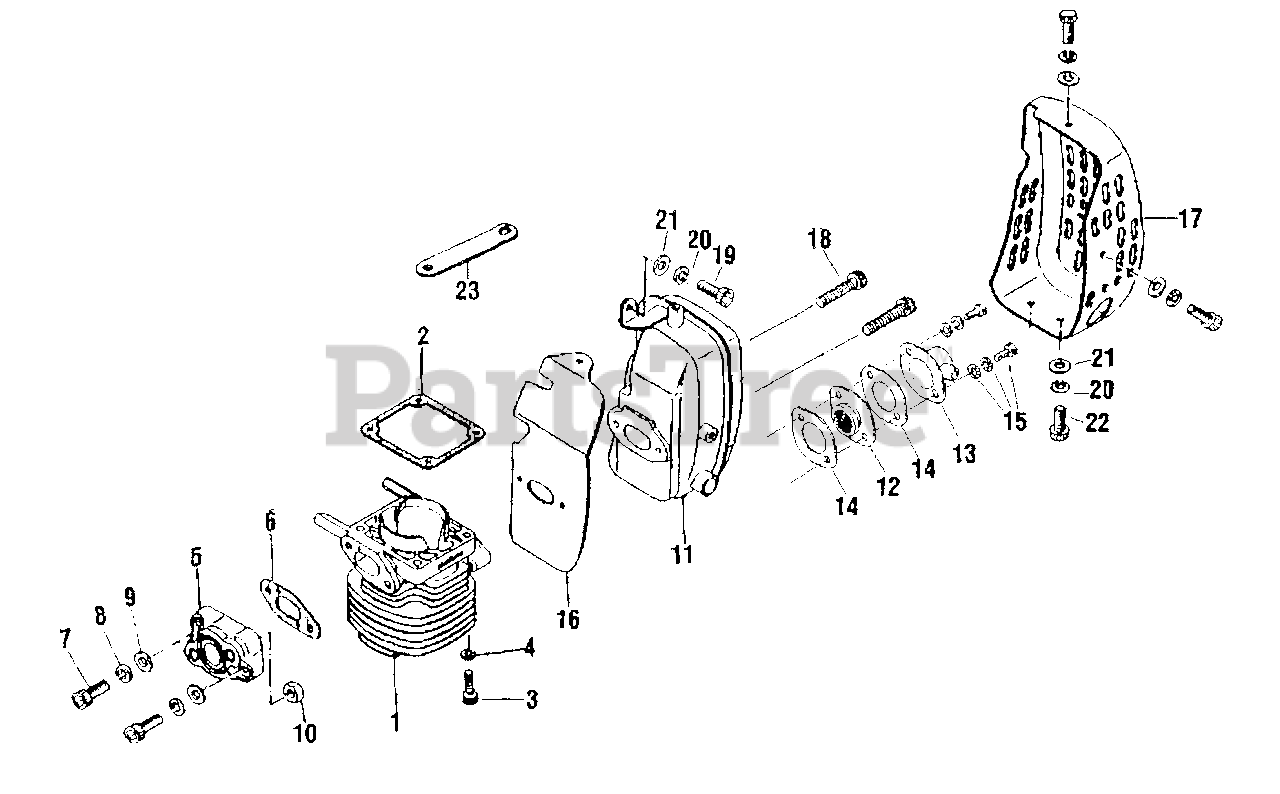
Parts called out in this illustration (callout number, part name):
1	CYLINDER
2	GASKET, CYLINDER
3	SCREW - 5X25
4	LOCKWASHER - 5
5	INSULATOR
6	GASKET, INTAKE
7	SCREW - 5X25
8	LOCKWASHER - 5
9	WASHER - 5
11	MUFFLER
12	SCREEN, SPARK ARRESTOR
13	GUIDE, EXHAUST
14	GASKET, EXHAUST
15	SCREW - 4X8
16	SHIELD, EXHAUST
17	GUARD, MUFFLER
18	SCREW - 6X25
19	SCREW - 5X12
20	LOCKWASHER - 5
21	WASHER
22	SCREW - 5X10
23	STAY, MUFFLER
